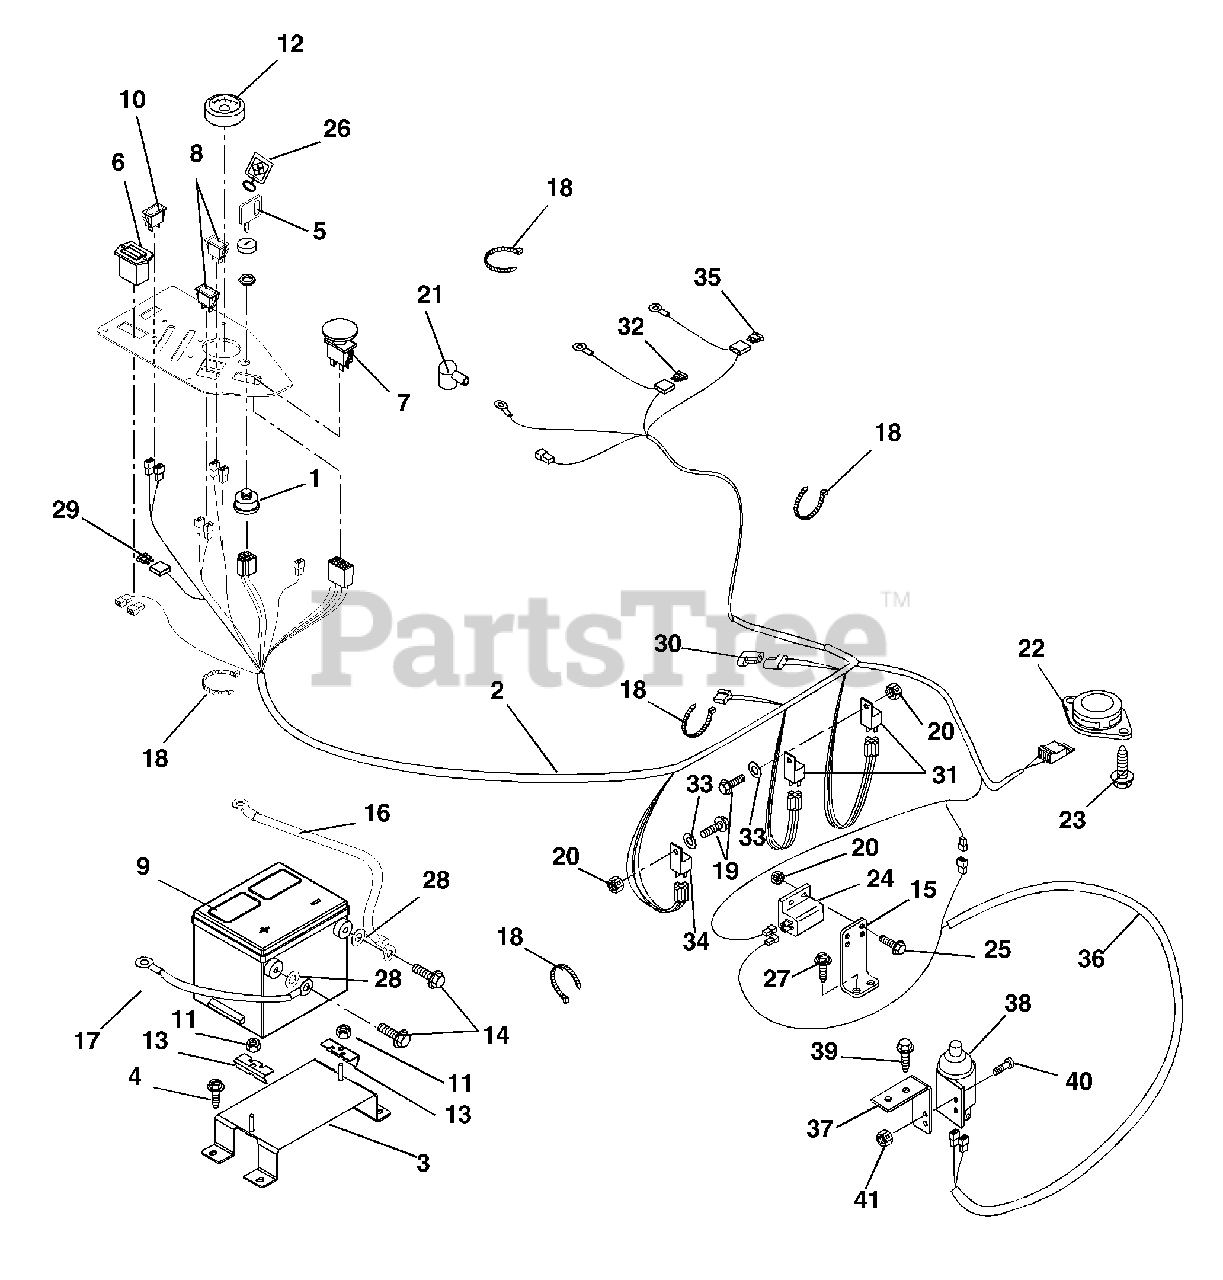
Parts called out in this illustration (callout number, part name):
1	Key Switch (036, 037)
1	Key Switch (038, 039, 309)
2	Harness, Wire (Gas) (036, 037)
2	Harness, Wiring (Diesel) (038, 039, 309)
3	Weldment, Battery Support
4	Screw-Tapping .38-16 x .75 Hex Washer Head
5	Key-with Cap (038, 039, 309)
5	Ignition Key Set (036, 037)
6	Hour Meter
7	Switch-Clutch With Retainer Ring
8	Light-Indicator Kit
9	Battery with Tube
10	Switch, Light
11	Nut-Locking-Nylon .312-18
12	Gauge, Temperature
13	Bracket, Battery Hold-Down
14	Bolt-Hex .25-20 x .75 Grade 5
15	Mount, Safety Switch
16	Positive Cable (036, 037)
16	Positive Cable (038, 039, 309)
17	Ground Cable (036, 037)
17	Cable, Negative Battery (038, 039, 309)
18	Cable Tie
19	Screw-Machine 10-24 x .75 Hex Washer Head (036, 037)
19	Screw-Machine 10-24 x .75 Hex Washer Head (038, 039, 309)
20	Nut-Locking-Nylon 10-24 With Insert (036, 037)
20	Nut-Locking-Nylon 10-24 With Insert (038, 039, 309)
21	Battery Terminal Boot, Red
22	Seat Switch
23	Screw-Tapping 12-24 x .50 Hex Washer Head
24	Switch-Single Pole
25	Screw-Machine 10-24 x .75 Hex Washer Head
26	Key Chain
27	Screw-Tapping .25-20 x .50 Hex Washer Head
28	Washer-Flat-Steel .406 x 1.00 x .188
29	Fuse, 7.5 Amp
30	Molded Diode Plug-Black 1-Amp
31	Relay
32	Fuse, 30 Amp
33	Washer-Flat-Steel .25 x .562 x .049 (038, 039, 309)
35	Fuse, 25 Amp
35	Fuse, 40 Amp
36	Harness, Wire Adapter CE (309)
37	Mount- Switch (309)
38	Switch-Single Pole (N.O.) with Cover (309)
39	Screw-Tapping .31-18 x .50 Hex Washer Head (309)
40	Screw-Machine 10-24 x .75 Hex Washer Head (309)
41	Nut-Locking-Nylon 10-24 with Insert (309)
